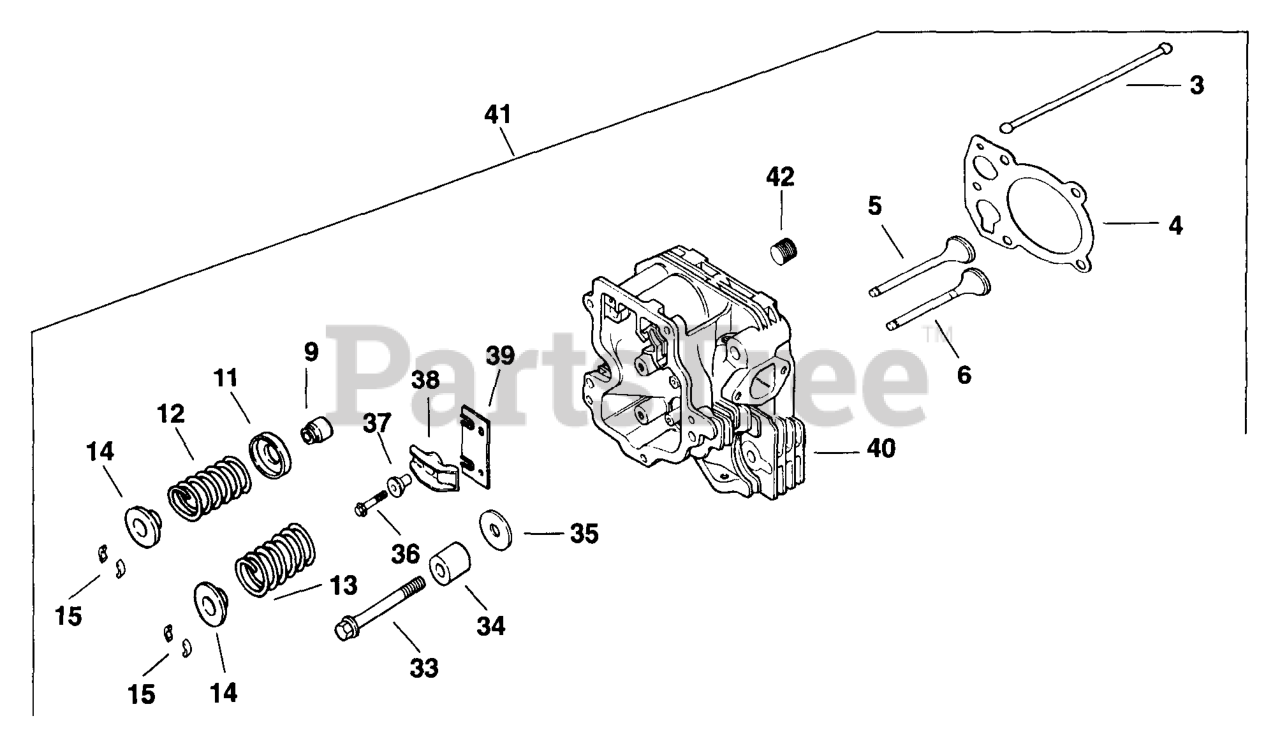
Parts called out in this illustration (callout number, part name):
3	Rod, Push
4	Gasket, Cylinder Head
5	Valve, Intake (Std.)
5	Valve, Intake (.25 O.S.)
6	Valve, Exhaust (Std.)
6	Valve, Exhaust (.25 O.S.)
9	Seal, Valve Stem
11	Spring, Retainer
12	Spring, Intake Valve
13	Spring, Exhaust Valve
14	Cap, Valve Spring
15	Kit, Retainer
41	Kit, Cylinder Head
42	Plug, Allen Hd. 1/8" Pipe
